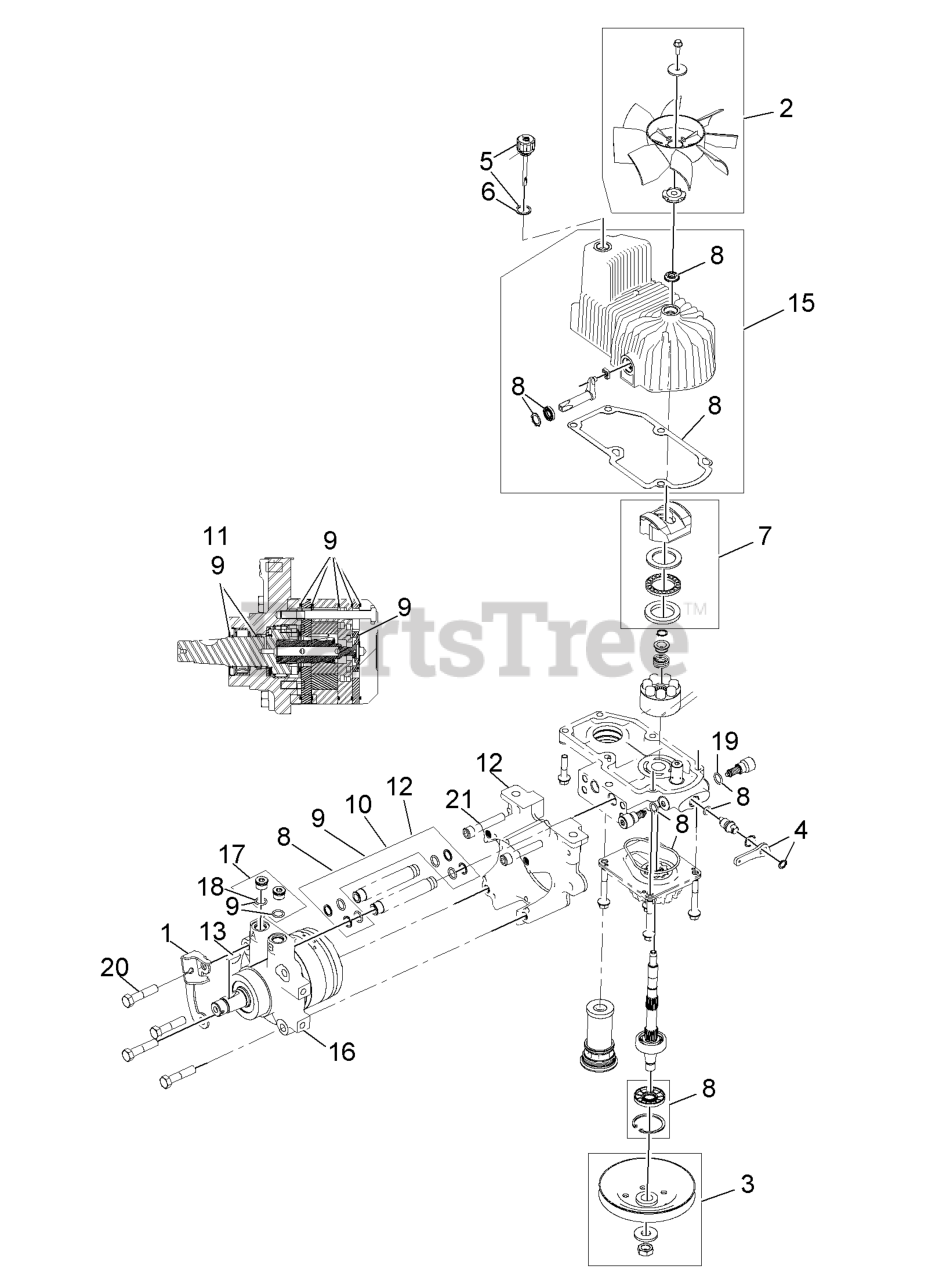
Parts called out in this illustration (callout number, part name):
1	BRACKET-ANCHOR, CABLE
2	FAN KIT
3	PULLEY KIT
4	HANDLE-BYPASS VALVE, HYDRO
5	DIPSTICK-HYDRO W/GASKET
6	GASKET-DIPSTICK, HYDRO
7	SWASH BLOCK KIT
8	PUMP SEAL KIT
9	MOTOR SEAL KIT
10	TUBE SEAL KIT
11	OUTPUT SHAFT SEAL KIT
12	NOSE CUP-UHT
13	KEY-WOODRUFF
15	HOUSING-HYDRO, LH
16	MOTOR-HYDRAULIC, LH 280CC
17	MAGNETIC PLUGS SERVICE KIT
19	O-RING-CHECK VALVE
20	SCREW HH
21	SCREW-HSH
